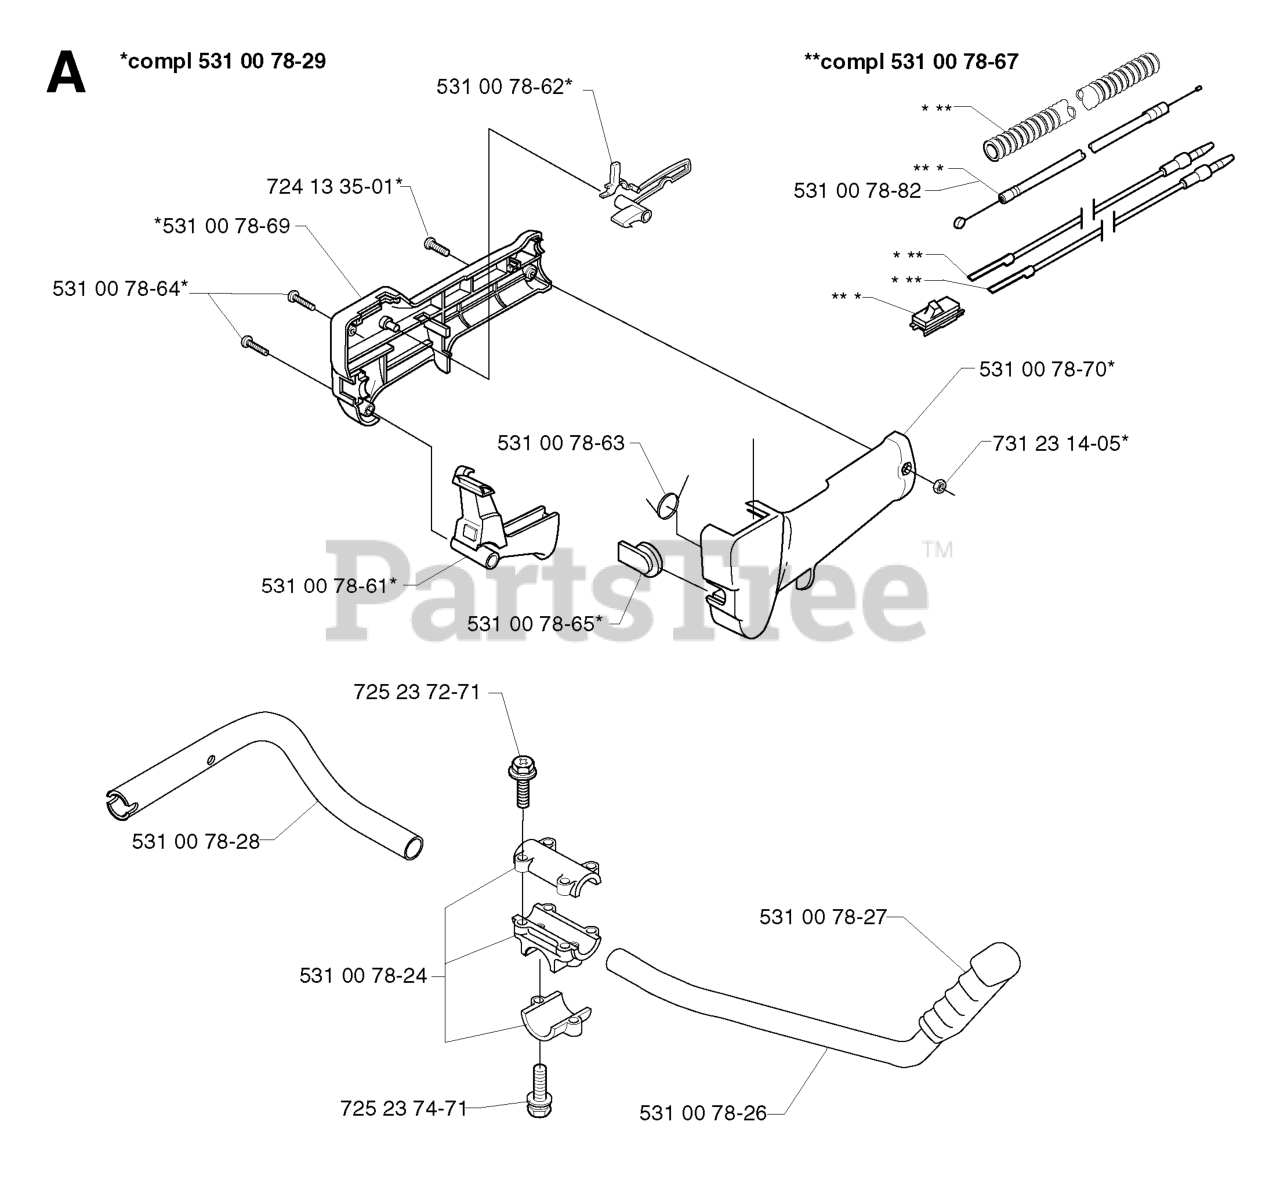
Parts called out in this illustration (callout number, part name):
1	DECK SVC W/DECALS.52.GTH.ORG
2	MANDREL.DECK.ASSEMBLY
3	WASHER-SPACER
4	RB PULLEY.IDLER.DRIVEN
5	LOCKNUT - 9/16
6	WASHER HEAD SCREW
7	DISCHARGE CHUTE 52"
8	SPRING - TORSION
9	PIN-CLEVIS 5/16 DIA X 5.19 ZD
10	BLADE, 17.75 X 2.5 X .25
11	BLADE BOLT ASSY-7/16" TB REPL
12	PLATE.52".CONFINEMENT.BLACK
13	CARRIAGE BOLT 5/16C X 5/8"
14	NUT 5/16 NYLOC
15	STUD.FASTNER.W/ANTI-ROTATE
16	5/16-18 NYLOC FLANGE NUT
17	PULLEY.IDLER.MWR.STATI.LH
18	ARM, IDLER, 52" BLK
19	PULLEY.IDLER.FLAT
20	PULLEY, IDLER
21	BUSHING, IDLER
22	GAUGE WHEEL
23	SHOULDER BOLT 1/2X2-5/8 ZD SPE
24	NUT 3/8-16 HEX FLG NYLOC ZD
25	SHIELD.BELT.LH.ORANGE
27	U-CLIP 5/16-18 NUT RETAINER
28	HCS 3/8-16 X 3-1/2 GR5 ZD
29	SPINDLE WASHER
30	WASHER 3/8 FLAT
31	NUT 3/8-16 NYLOC
32	RHSNB 3/8-16X1-3/4
33	WASHER 7/16 FLAT ZD
35	7/16-14 HEX NUT W/NYL RING ZD
36	ARM.SUSPENSION.MOWER
37	SB 3/8-16 X 3/8 SKT HD ZD
38	WASHER 3/8 SAE FLAT
39	NUT HEX 3/8-16 NYLON, THIN
40	NOSE ROLLER 48"
41	ROD.ROLLER.NOSE.NARROW.48"
42	PIN.COTTER.5/16.BOW TI
43	WASHER 5/16 FLAT
44	SHIELD BELT RH 52
45	HCS 5/16C X 1
46	WASHER.LOCK.HVY.HLCL.SPR.5/16
47	DECAL, NO STEP
48	DECAL, CAUTION
49	DECAL.MOWER.SCH.48/54
50	PORT.WASHOUT
51	BOLT 1/4-20 X 1/2 HWST
52	BOLT 7/16-14 X 2-1/2 GR 5 ZD
53	BELT, 143.5" EL
54	BELT GAURD
55	EYE BOLT 5/16 X 3.50
56	NUT 5/16C WHIZ
58	BEARING, BALL
59	RP PULLEY, COLLECTION 48
60	RETAINER CLIP
